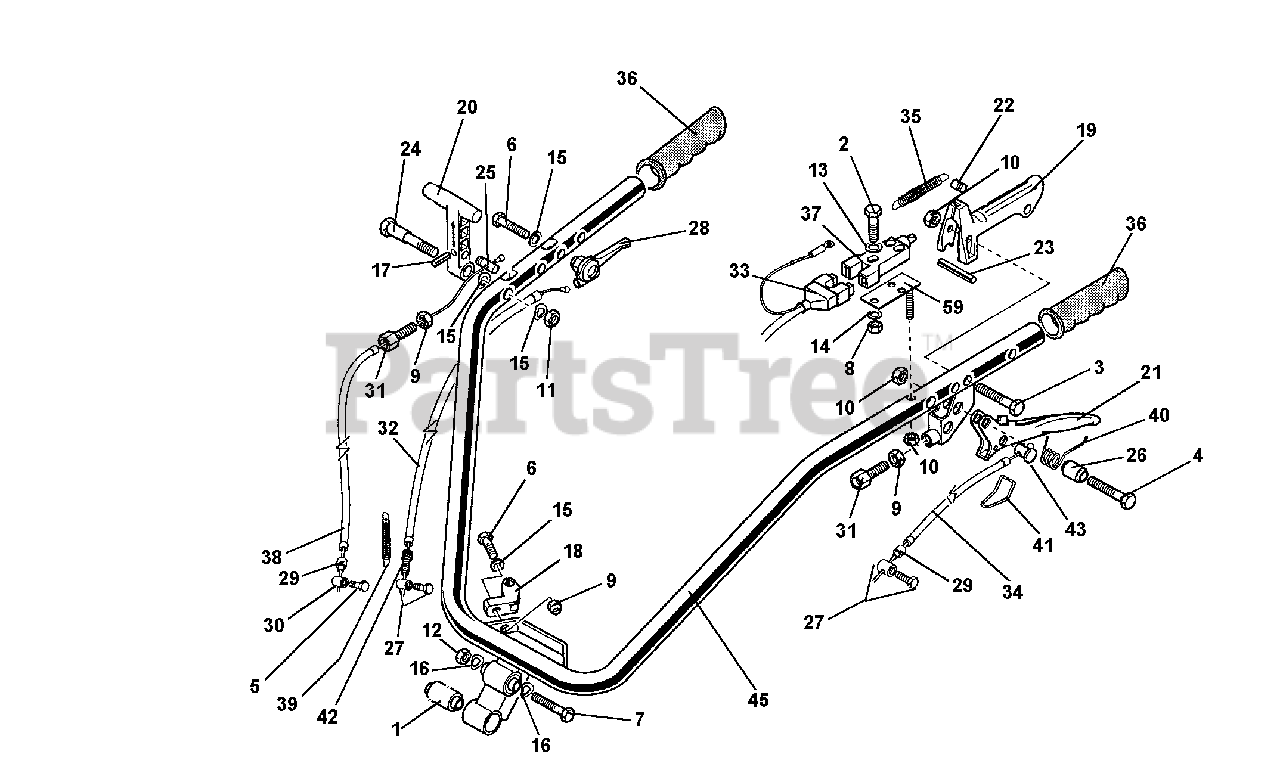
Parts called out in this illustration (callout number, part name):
1	SILENTBLOCK
2	SCREW TE M4X25
3	SCREW, TE M6X45
4	SCREW, M6X25
5	SCREW, TE M6X16
6	SCREW, M8X35
7	SCREW, M10X80
10	NUT, SELF LOCKING M6
13	FLAT WASHER, M4.3
14	LOCK WASHER, M4.3
15	LOCK WASHER, M8.4
16	WAVE WASHER, M10.4
17	PIN, LOCKING, M4X20
18	SUPPORT, CONTROL ROD
19	MOTOR STOP LEVER
20	REVERSER LEVER
21	CLUTCH LEVER
23	LEVER STOP FOR MOTOR STOP
25	DRILLED PIN
26	LEVER SPACER
27	CLAMP, CABLE
28	LEVER, ACCELERATOR
30	PIN, CABLE CLAMP
31	SCREW, ADJUSTING, M8
32	THROTTLE CABLE
33	SWITCH WIRING HARNESS
34	CLUTCH CABLE
37	STOP SWITCH
38	REVERSER CABLE
39	SPRING, KOHLER ENGINE
40	LEVER SPRING
42	CABLE ADJUSTER
44	SWITCH PLATE
